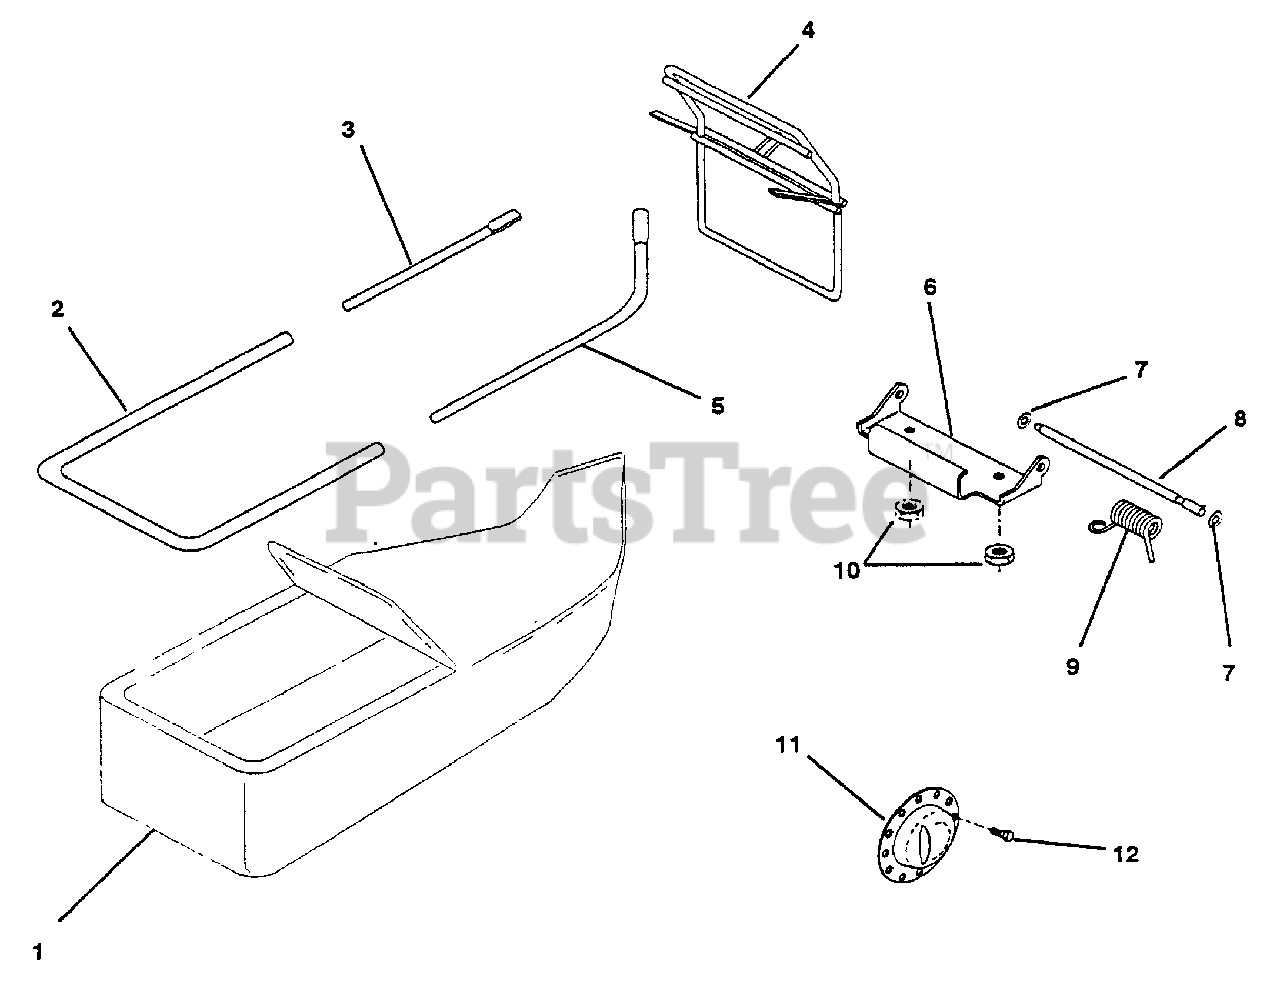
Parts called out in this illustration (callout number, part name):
1	Grass Bag
2	Frame, Upper
3	Side Tube, LH
4	Frame, Lower
5	Side Tube, RH
6	Hinge Bracket
7	Nut, Push
8	Rod, Hinge
9	Spring, Torsion
10	Locknut
11	Deflector, Muffler
12	Screw
